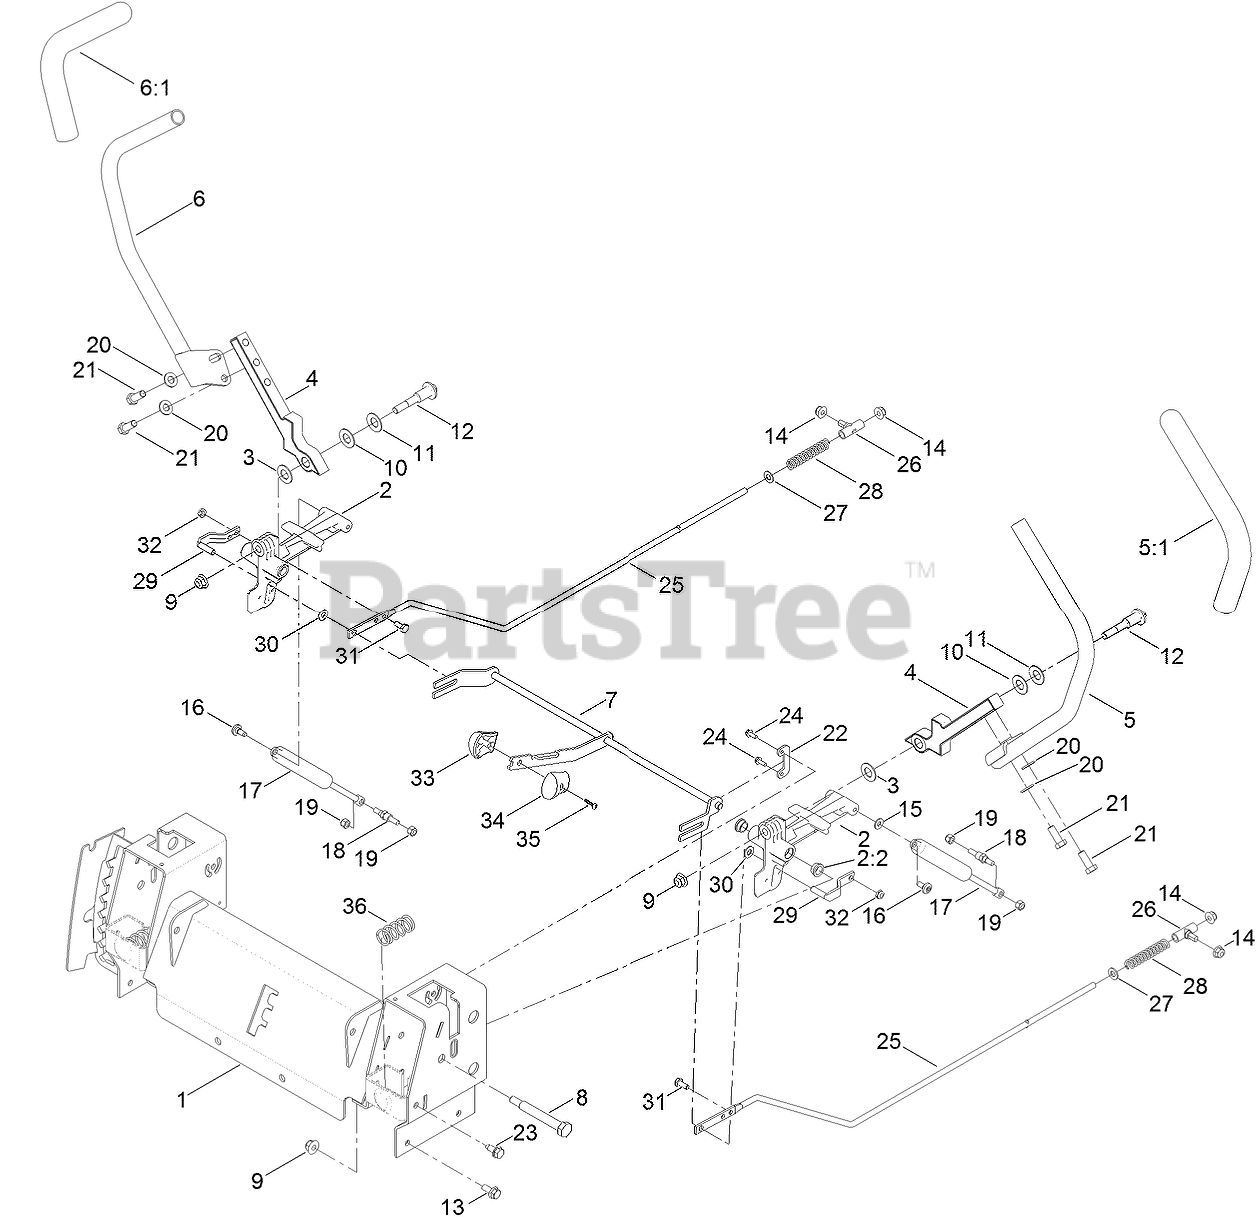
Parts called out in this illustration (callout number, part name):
1	CONTROL BOX ASM
2	ACTUATOR ARM ASM
2:2	BUSHING-FLANGE
3	WASHER-NYLON
4	ARM-CONTROL
5	HANDLE-CONTROL, LH
6	HANDLE-CONTROL, RH
7	SPEED CONTROL ASM
8	BOLT-PIVOT
9	NUT-HF, NI
10	WASHER
11	WASHER-BELLEVILLE
12	BOLT-PIVOT
13	SCREW-HHF
14	NUT-HF, NI
15	WASHER
16	SCREW-SHOULDER
17	DAMPER
18	STUD-DAMPER
19	NUT-LOCK, NI
20	WASHER-FLAT
21	SCREW-HH
22	RETAINER
23	SCREW-HWHTF
24	SCREW-TAPTITE
25	ROD-HYDRO
26	MOUNT-ROD, HYDRO
27	WASHER-PLAIN
28	SPRING-RETURN, NEUTRAL
29	PIN-ROD, HYDRO
30	SPACER-NYLON
31	SCREW-HH
32	NUT-LOCK, NI
33	KNOB-RH
34	KNOB-LH
35	SCREW-PPH
36	SPRING-RETURN
